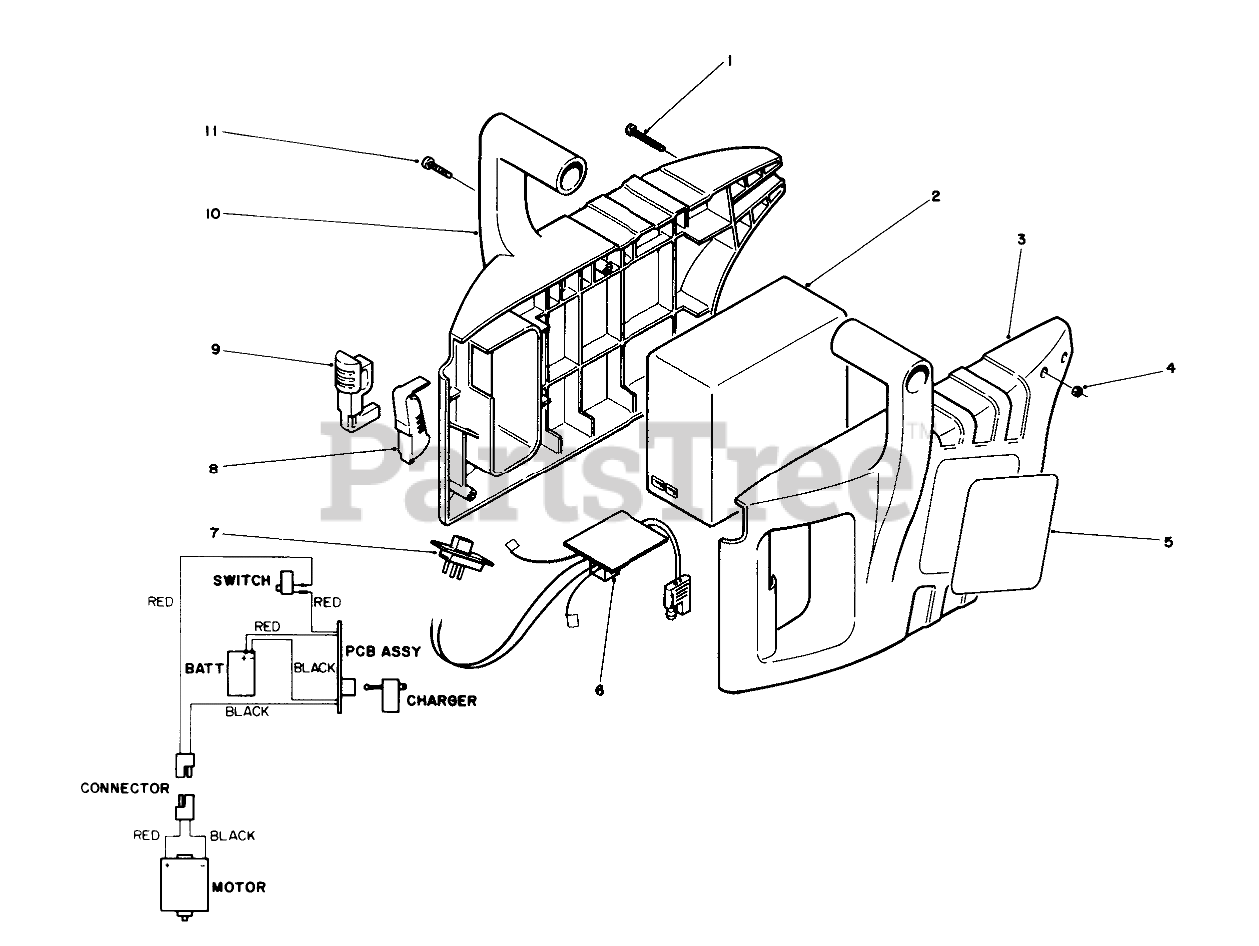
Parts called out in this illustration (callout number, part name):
1	SCREW-PPH
2	BATTERY
3	RH BATTERY CASE/HNDL
4	NUT-HEX
5	DECAL - 7" TRIM
6	Wiring Harness
7	SWITCH
8	TRIGGER
9	TRIGGER LOCK
10	LH BATTERY CASE/HNDL
11	Screw
